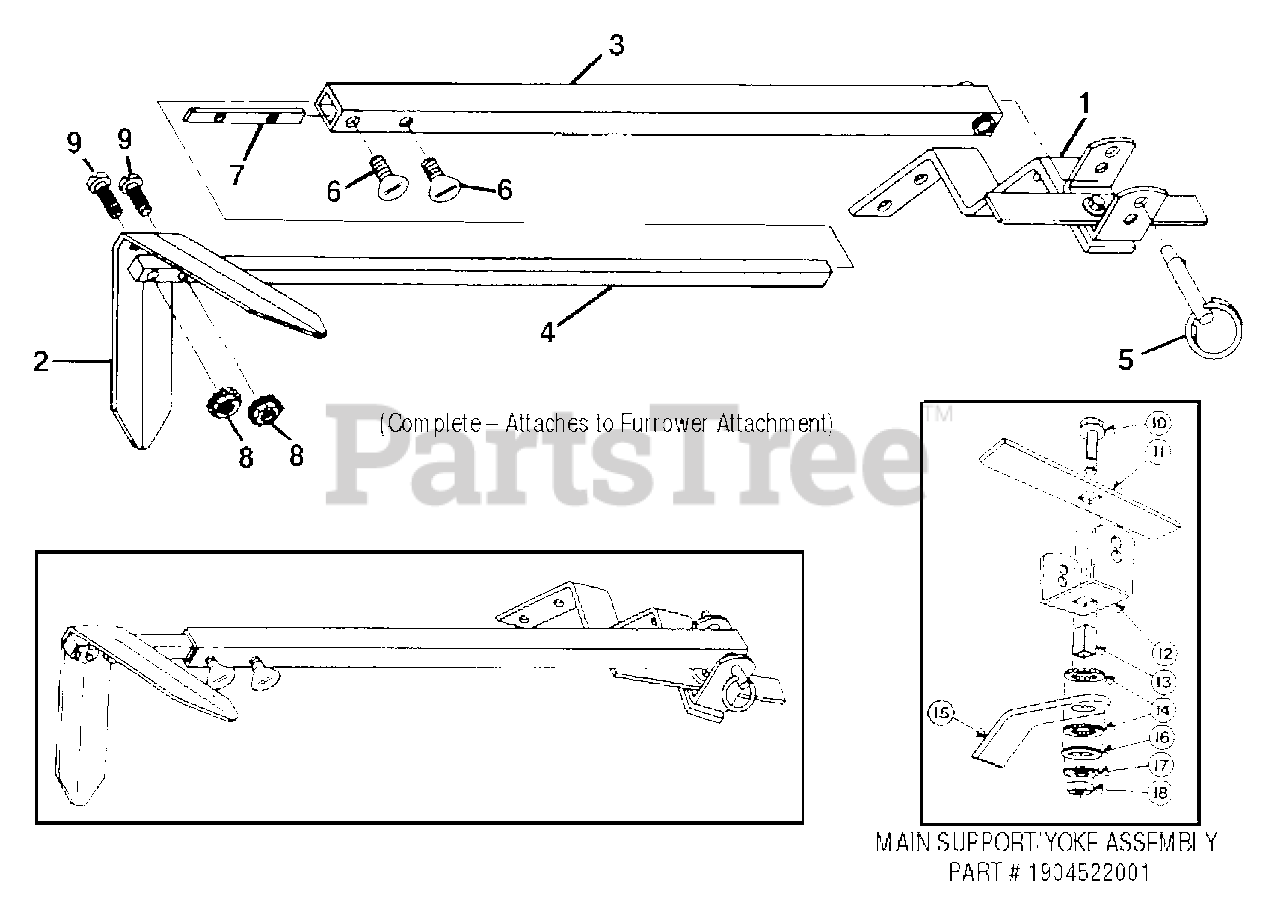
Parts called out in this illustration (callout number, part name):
1	Complete Main Support & Yoke Assy.
2	Marker Blade
3	Marker Arm
4	Marker Extension Arm
5	Hitch Pin
6	Thumbscrew, 1/4-20 x 1/2
7	Nut Bar
8	Hex Nut, #10-24 w/attached start washers
9	Round Hd. Screw, #10-24 x 1
10	Hex Flange Screw, 3/8-16 x 1-1/2'
11	Stop Bar
12	Yoke.
13	Tube Key (square)
14	Friction Washer
15	Main Support
16	Washer (square hole)
17	Disc Spring Washer
18	Hex Nut, 3/8-16
